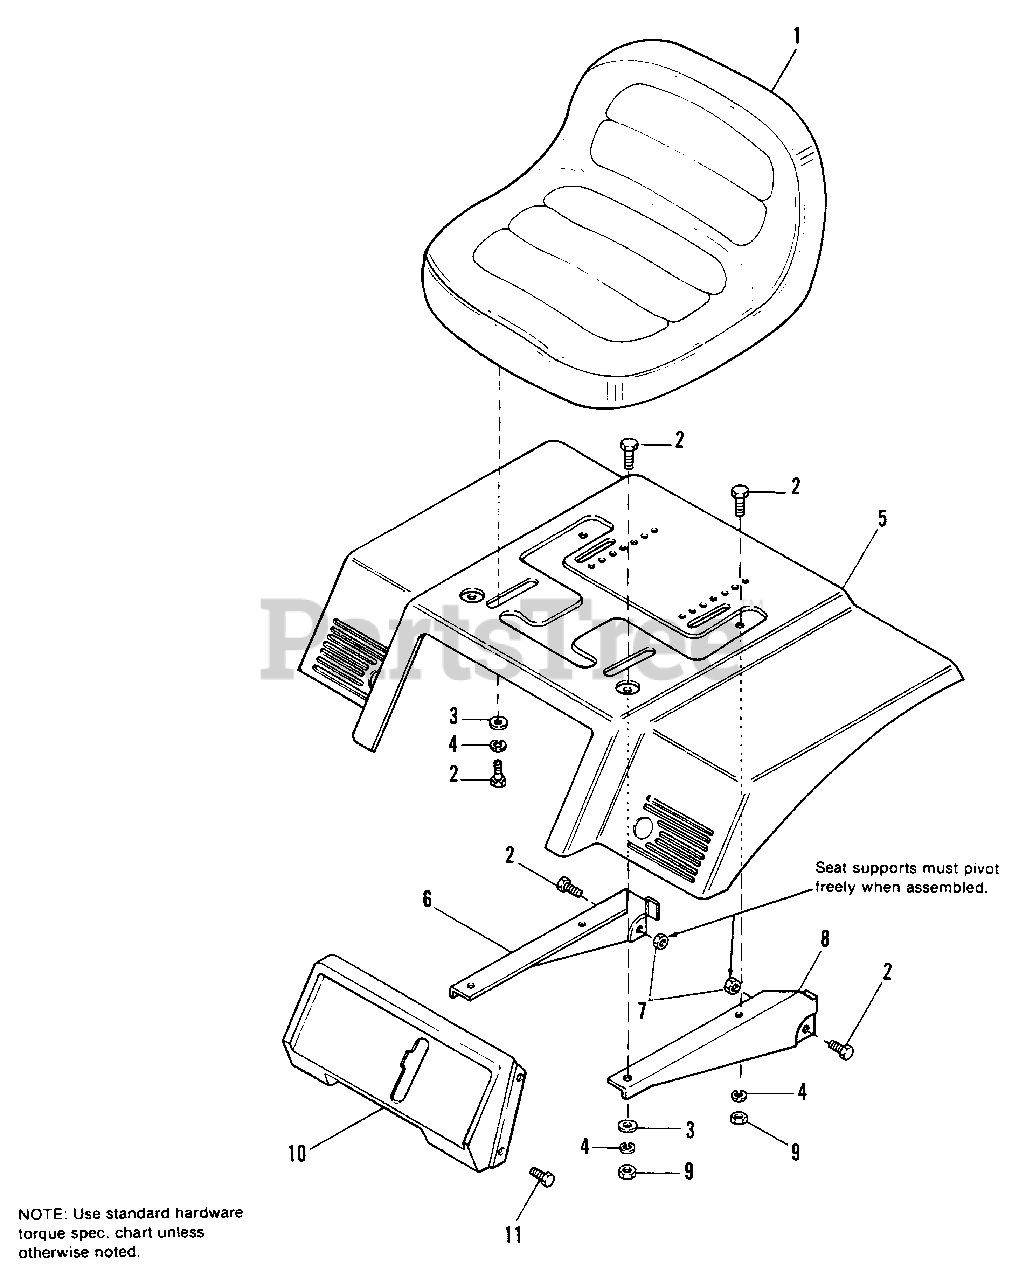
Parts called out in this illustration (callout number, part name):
2	CAPSCREW, 5/16-18 x 3/4
3	WASHER, 5/16
4	LOCKWASHER, 5/16
5	DECK, Seat
6	SUPPORT, Seat. R.H.
7	NUT, Hex, 5/16-18
8	SUPPORT,eat. L.H.
9	NUT, Hex, 5/16-18
10	PANEL, Shift
11	SCREW, Taptite, 1/4-20 x 1/2
